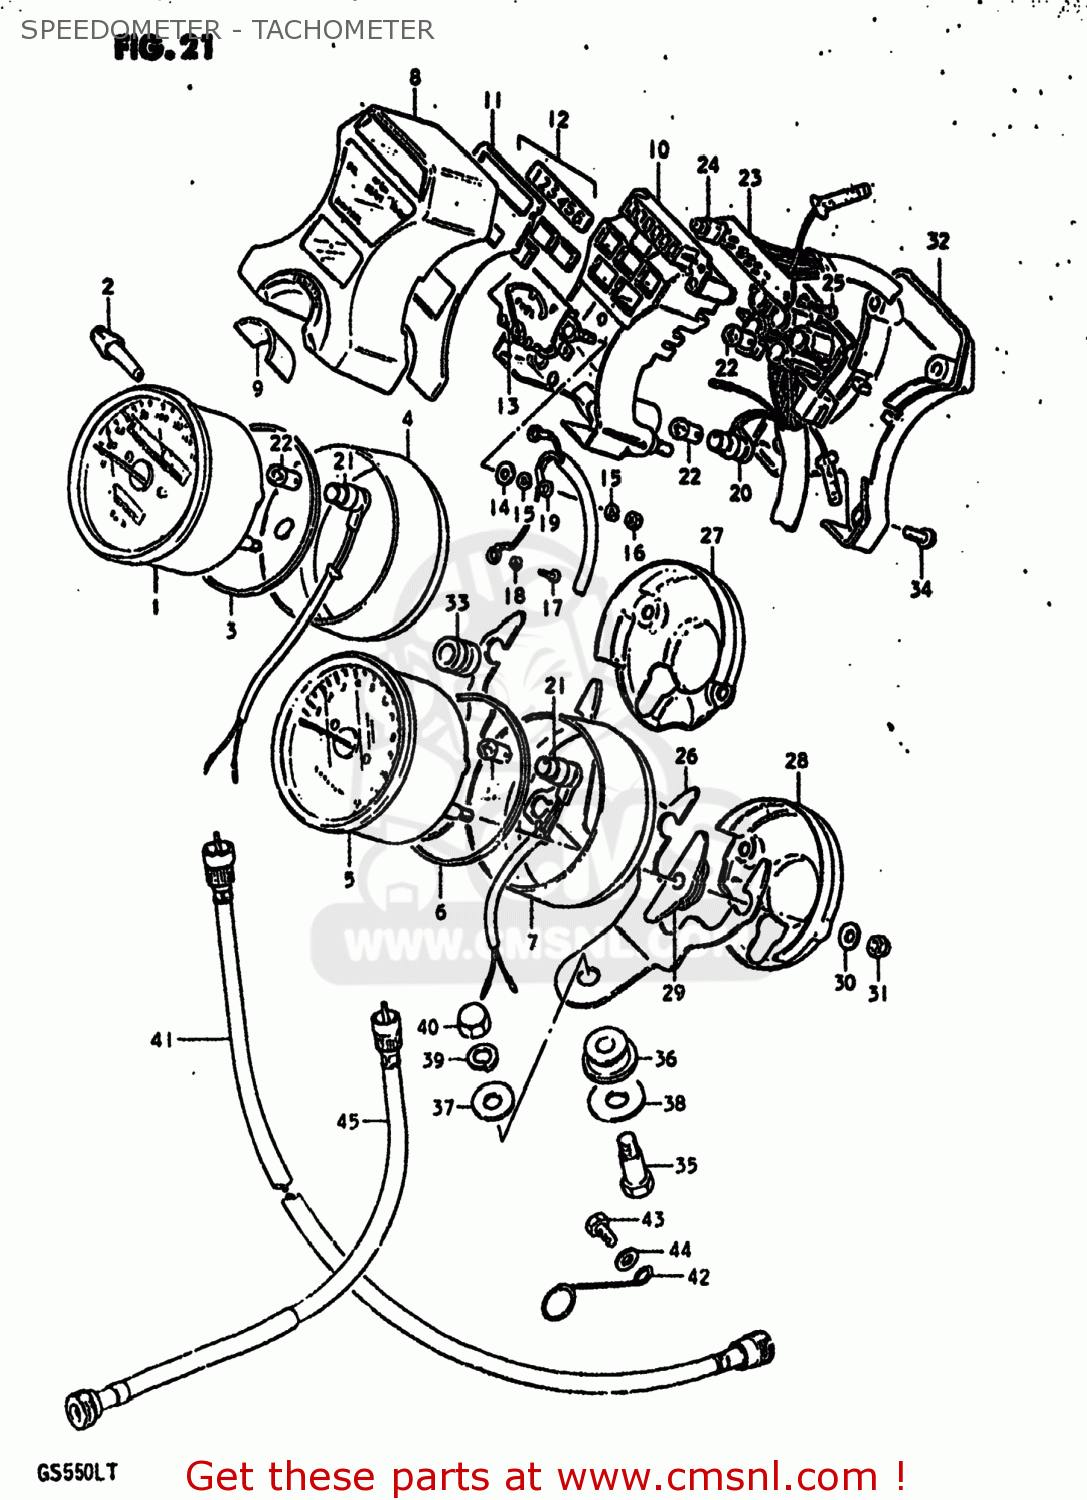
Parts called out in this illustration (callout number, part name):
1	METER,SPEEDOMETER
2	KNOB
3	CUSHION
4	COVER,SPEEDOMETER
5	TACHOMETER
6	CUSHION
7	COVER,TACHOMETER
8	CASE,PILOT BOX,OUTER
9	SEAL,IGNITION SWITCH
10	CASE, PILOT BOX INNER
11	PLATE,PILOT BOX
12	LENS SET,PILOT
13	METER,FUEL
14	WASHER
15	LOCK WASHER
16	NUT
17	SCREW
18	LOCK WASHER
19	LEAD WIRE, FUELMETER
20	SOCKET
21	SOCKET,METER
22	BULB(12V3.4W,STANLEY,A72A)
23	INDICATOR ASSEMBLY,GEAR POSITION
24	BULB(14V1.12W)
25	SCREW
26	BRACKET,COMBINATION METER
27	ORNAMENT,SPEEDOMETER
28	COVER,TACHOMETER
29	CUSHION,METER
30	WASHER
31	NUT
32	COVER,PILOT BOX,UNDER
33	CUSHION,PILOT BOX
34	SCREW,PILOT BOX
35	BOLT(8X31)
36	CUSHION
37	WASHER(8.5X23X1.2)
38	WASHER
39	LOCK WASHER
40	NUT
41	CABLE ASSEMBLY,SPEEDOMETER
42	GUIDE,SPEEDOMETER CABLE
43	BOLT, UPPER
44	WASHER
45	CABLE ASSEMBLY,TACHOMETER
